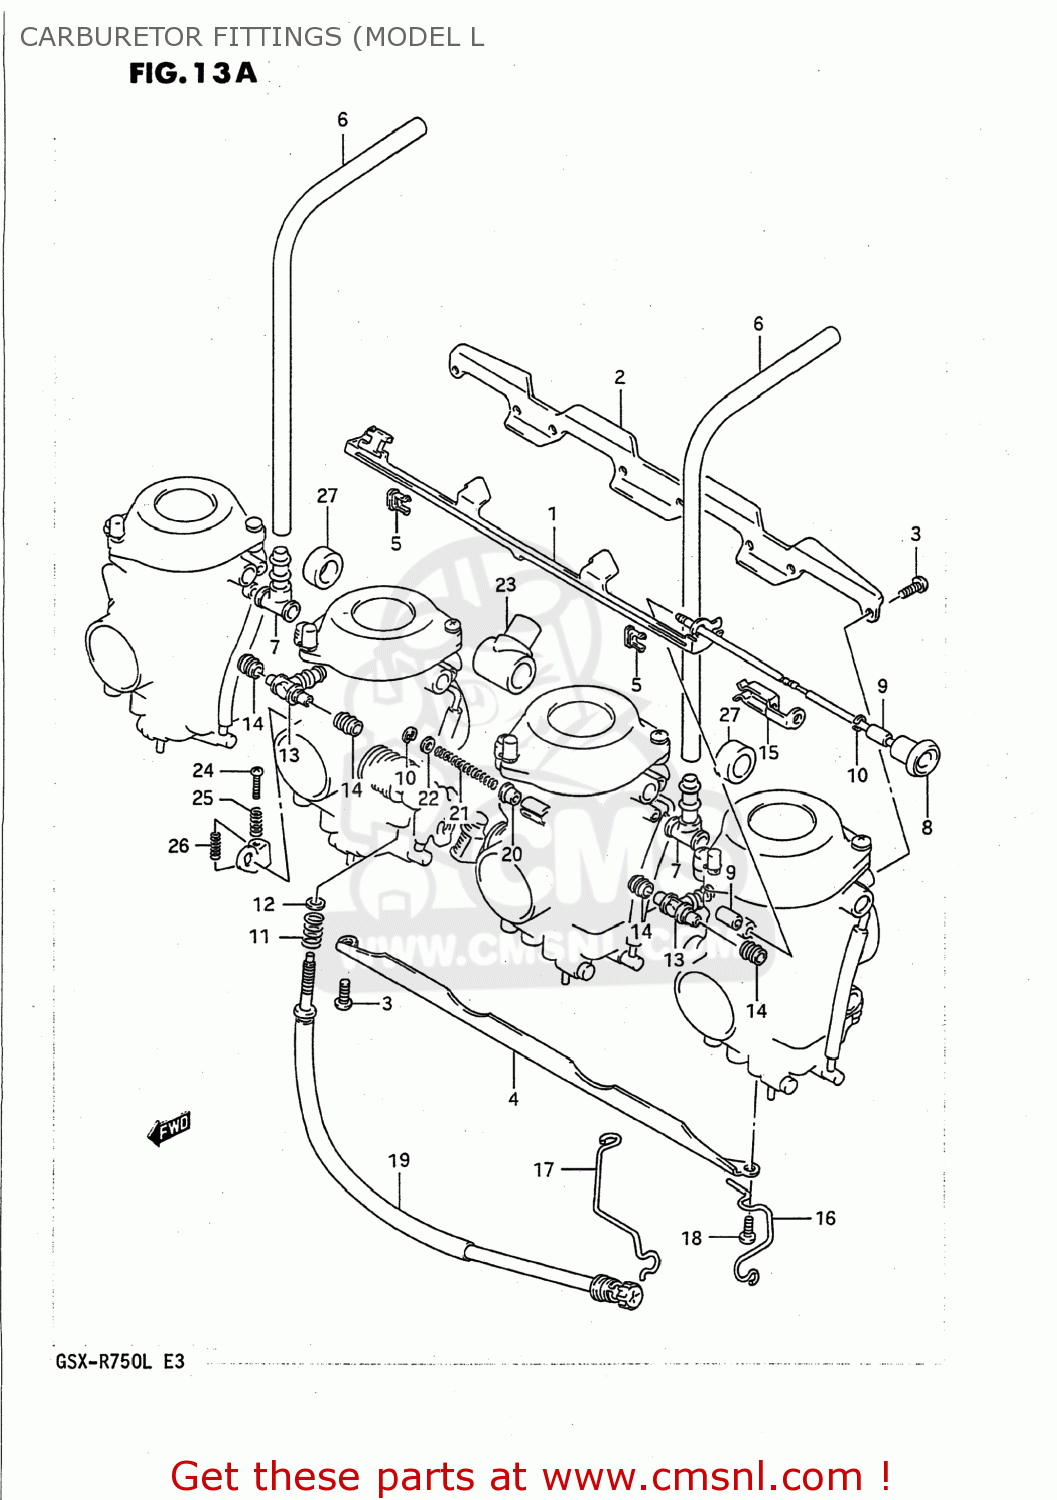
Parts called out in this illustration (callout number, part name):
1	LEVER
2	PLATE
3	SCREW
4	PLATE
5	HOLDER
6	HOSE
7	HOSE
8	SHAFT ASSY,STARTER
9	SPACER
10	E RING
11	SPRING
12	WASHER
13	NIPPLE
14	SEAL
15	PLATE
16	CLIP
17	CLIP
18	SCREW
19	ADJUSTER
20	RING
21	SPRING
22	WASHER
23	HOSE ASSEMBLY
24	SCREW
25	SPRING
26	SPRING
27	HOSE
